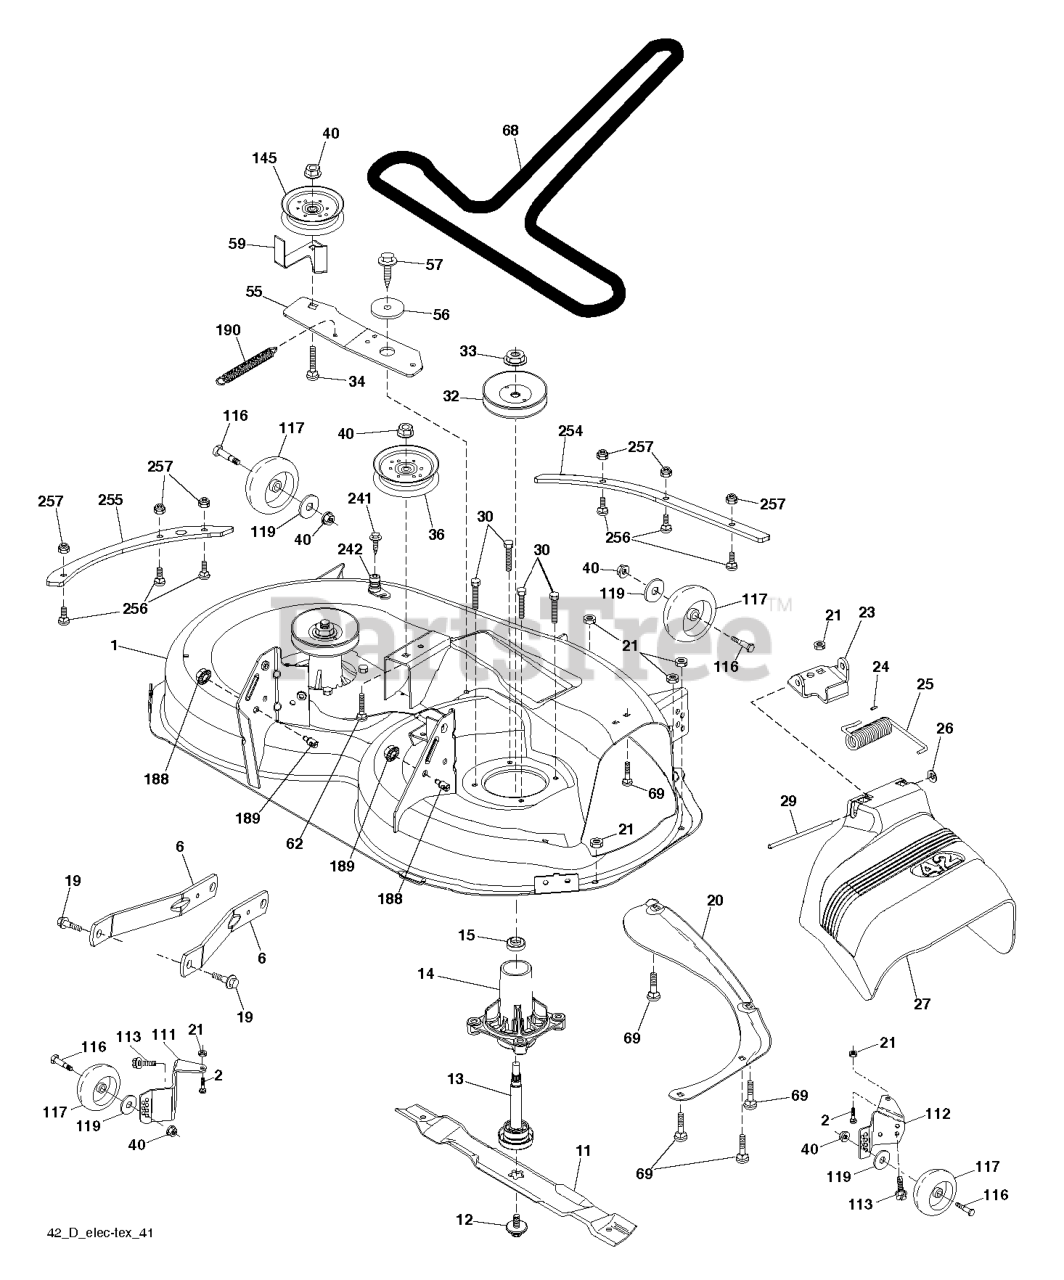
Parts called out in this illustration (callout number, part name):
1	DECK.SVC.42"2GW
2	RP BOLT 5/16-18 X3/4 ZN/YEL GR
6	ARM.SUSPENSION.MOWER.R
8	BOLT.WASHER.ASM.7/16-2
11	42" HI-LIFT BLADE
13	MANDREL.ASM.SUB-NON.GR
14	RP.HOUSING.MANDREL.4PT.
19	BOLT.SHOULDER
20	BAFFLE.VORTEX
21	LOCKNUT
23	BRKT.DEFLECTOR.38"2005+
24	CAP-SLEEVE LT
25	SPRING.TORSION.DEFLECT
26	NUT PUSH M
27	SHIELD.DEFLECTOR.MOWER.42"BLAC
29	ROD.HINGE
30	SCREW, WASHER HEAD
31	WASHER.SPACER.MANDREL
32	PULLEY/MANDREL
33	NUT.FLANGE.LOCK.TOP
34	BOLT.3/8-16X1.50
36	PULLEY.IDLER.2006
40	NUT LOCK FLG 3/8-16 UNC
55	IDLER.ARM.42"
56	SPACER.RETAINER
57	SCREW 3/8-16X1
59	GUARD, BELT
62	BOLT
68	BELT V SECONDARY
69	BOLT
111	BRKT.WHEEL.GAUGE.LH.42"
112	BRKT.WHEEL.GAUGE.RH.42"
113	BOLT.5/16HEX.WHS.HD
116	BOLT M
117	WHEEL.GAGE.HALF.SPOKED
119	WASHER.5/16.FLAT.STE.STD.
145	PULLEY.IDLER.48"PRIMARY
188	STUD.FASTNER.W/ANTI-ROTATE
189	NUT LOCK HEX FLANGE 5/16-18
190	SPRING.MOWER.DRIVE.ELECTRIC
241	SCREW.TT.#10-32X.5.3/8.FLANGE
242	PORT.WASHOUT
254	PLATES.RENFRC.42DECK.PT431FRNT
255	PLATES.RENFRCE.42DECK.X431SIDE
256	RHSNB, 1/4-20 X 1, GR5
257	NUT T
